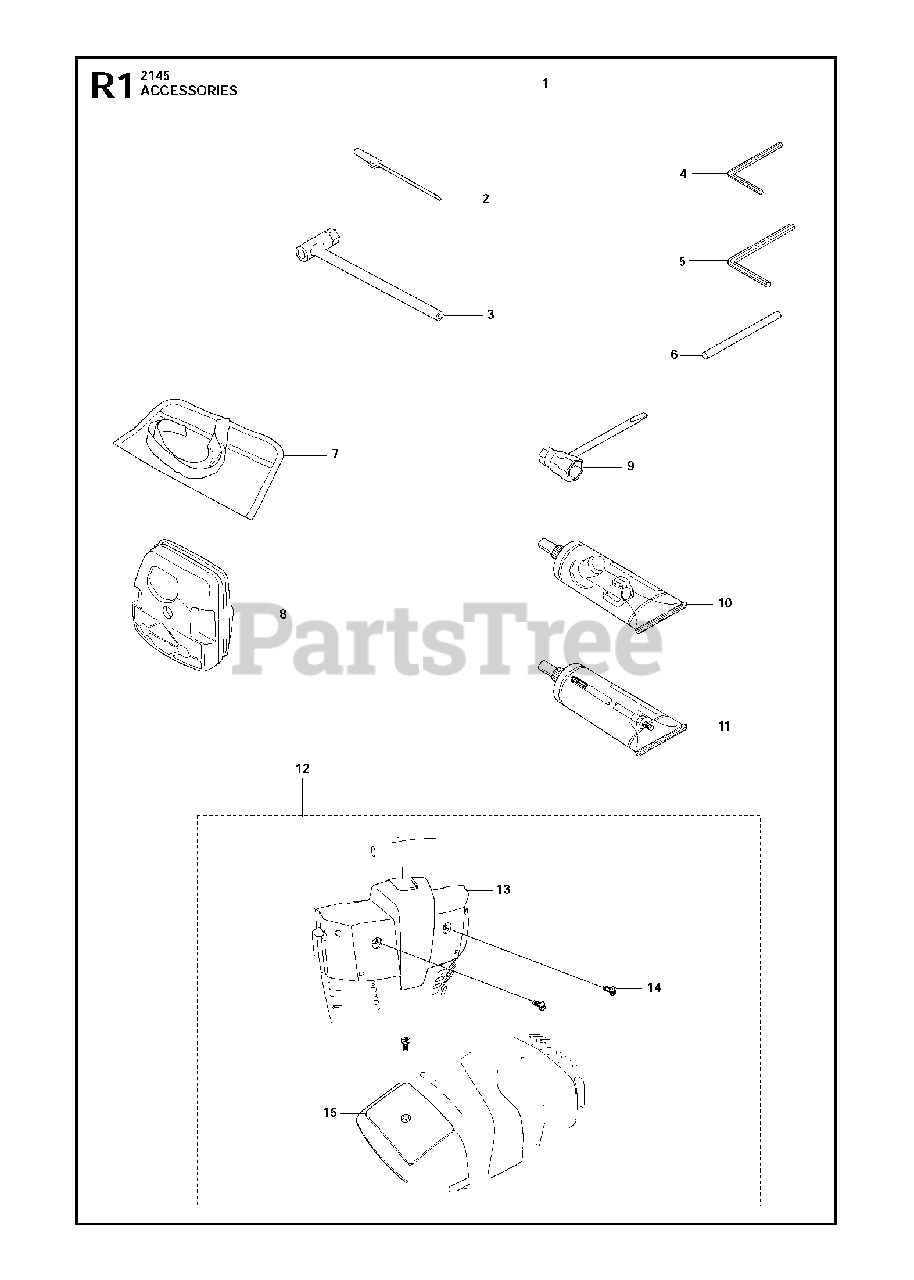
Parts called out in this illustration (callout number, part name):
1	TOOL KIT
2	SCREWDRIVER
3	SCRENCH
4	L-KEY WRENCH
5	L-SPANNER
6	LOCKING PIN
8	AIR FILTER
8	FILTER
9	COMBI TOOL
12	WINTER SET
13	COVER
14	SCREW
15	COVER
